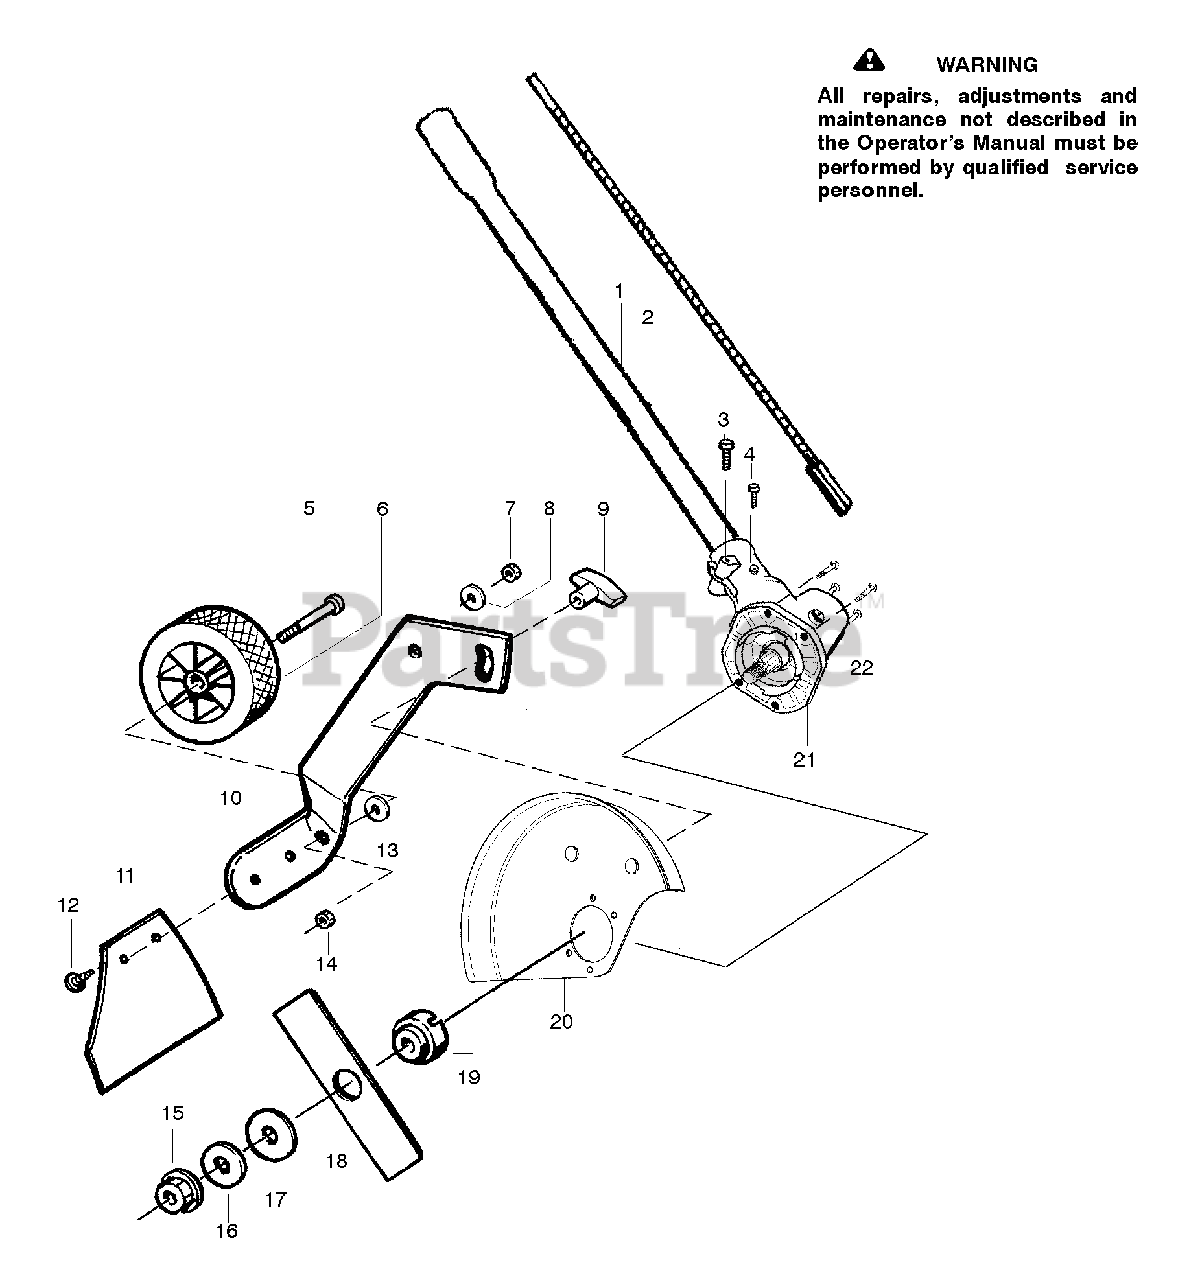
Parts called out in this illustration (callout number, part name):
1	Kit-Assy. Driveshaft
2	Flexshaft-Split boom
4	Screw-Alignment
5	Bolt-Shoulder Axle
6	Wheel-4"
10	Bracket-Adj. Wheel
11	Kit-Mud Flap
12	Fastener-Mud Flap
15	Nut-Flange
16	Washer-Belleville
17	Washer-Flat
18	Accy-7.5" Blade
20	Kit-Edger Guard
21	Kit-Gearbox
